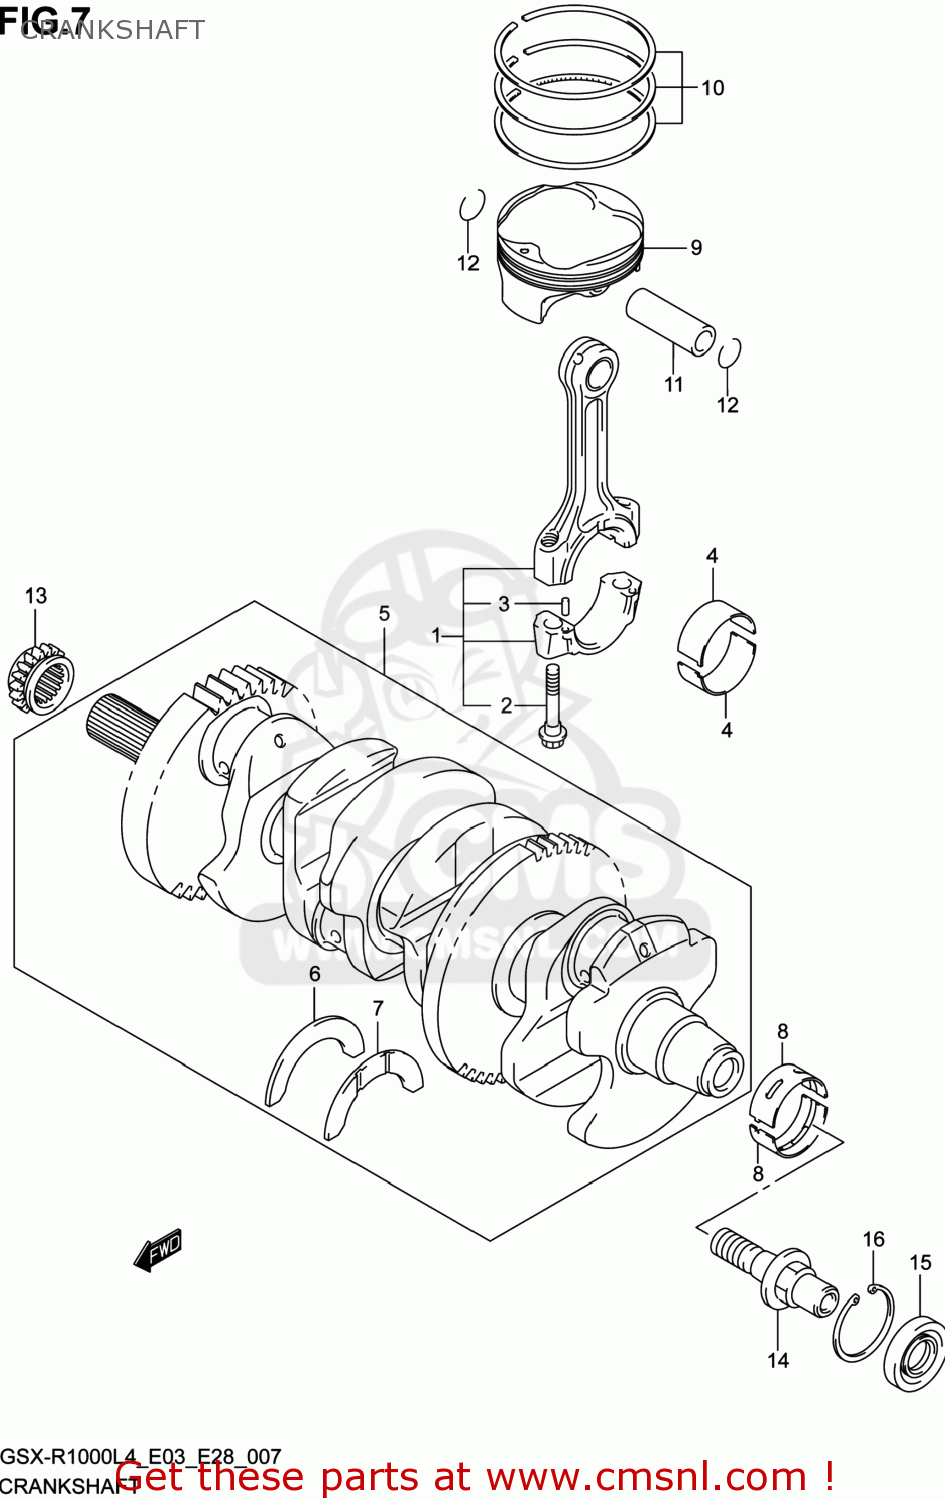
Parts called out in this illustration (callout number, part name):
1	CONNECTING ROD ASSY
2	BOLT,CONNECTING ROD
3	PIN,CONNECTING ROD
4	BEARING,CRANK PIN
5	CRANKSHAFT SET
6	BEARING,CRANK THRUST(GREEN)
7	BEARING,CRANK THRUST(RED)
8	BEARING,CRANKSHAFT
9	PISTON
10	RING SET,PISTON
11	PIN,PISTON
12	CIRCLIP
13	SPROCKET,CAM CHAIN DRIVE
14	BOLT,GENERATOR ROTOR
15	SEAL,OIL(14X30X8)
16	CIRCLIP
